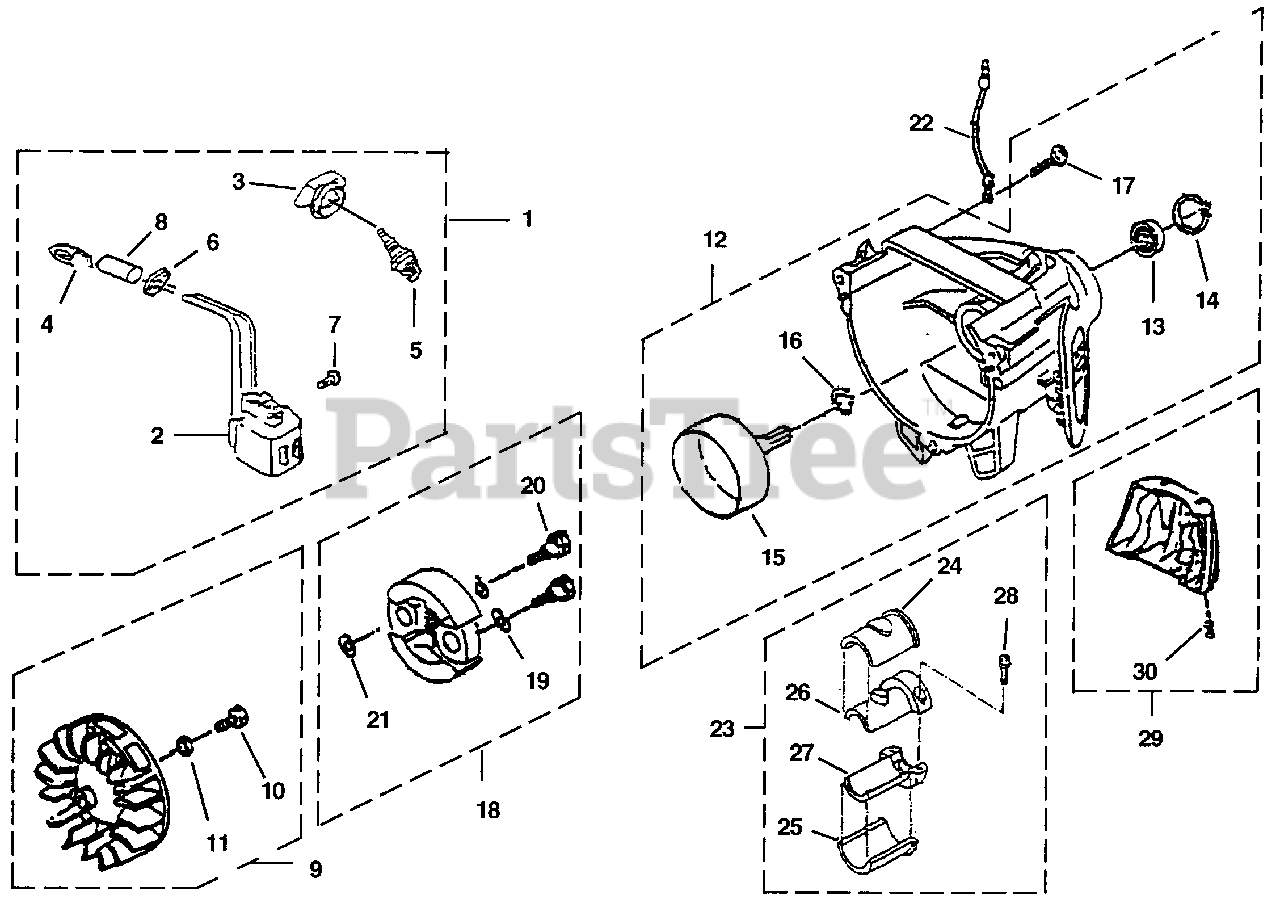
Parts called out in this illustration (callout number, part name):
1	IGNITION KIT
2	MODULE-Ignition
3	CAP-Plug
4	SPRING-Plug Cap
5	SPARK PLUG
7	SCREW ASSEMBLY (M4 x 20)
9	ROTOR ASSEMBLY
10	BOLT ASSEMBLY (M6 x 16)
12	CLUTCH HOUSING
13	BEARING-Ball
14	SNAP RING-Inner
15	CLUTCH DRUM
16	SNAP RING-Outer
17	SCREW-Socket Hd (M5 x 20)
18	CLUTCH ASSEMBLY
20	BOLT-Clutch (M6 x 25)
23	DRIVESHAFT ISOLATOR ASSEMBLY
26	ISOLATOR
27	ISOLATOR
28	SCREW-Socket Hd (M5 x 18 SW)
29	ENGINE STAND
30	SCREW ASSEMBLY (M5 X 14)
